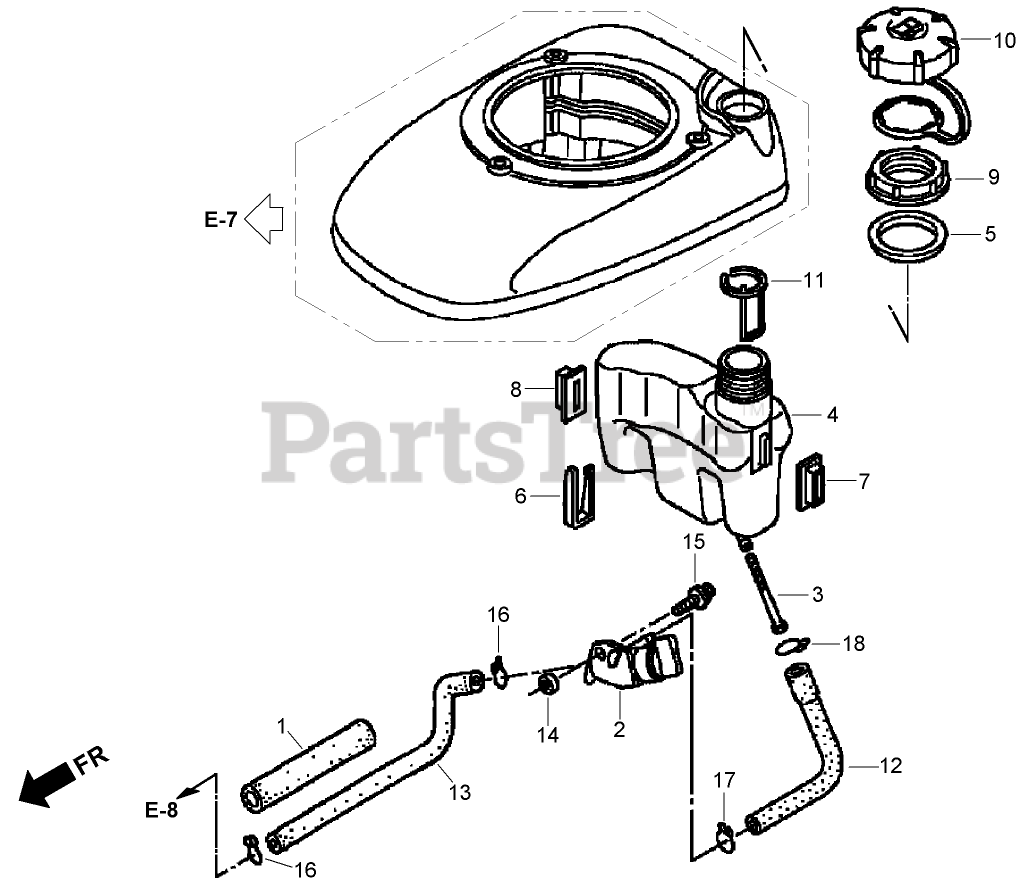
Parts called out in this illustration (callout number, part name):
1	SUPPORTER-RUBBER (107 mm)
2	PETCOCK ASM
3	FILTER-FUEL
4	TANK-FUEL
5	SEAL-NECK, FUEL FILLER
6	CLIP-MOUNTING, TANK
7	RUBBER A-MOUNTING, TANK
8	RUBBER B-MOUNTING, TANK
9	NUT-MOUNTING, TANK
10	FUEL TANK CAP ASM
11	GAUGE-LEVEL, FUEL
12	TUBE-TANK, FUEL
13	TUBE-FUEL
14	COLLAR-PETCOCK, FUEL
15	SCREW-WASHER (5X10)
16	CLIP-TUBE (B8)
17	CLIP-TUBE (B10)
18	CLIP-TUBE (C11)
